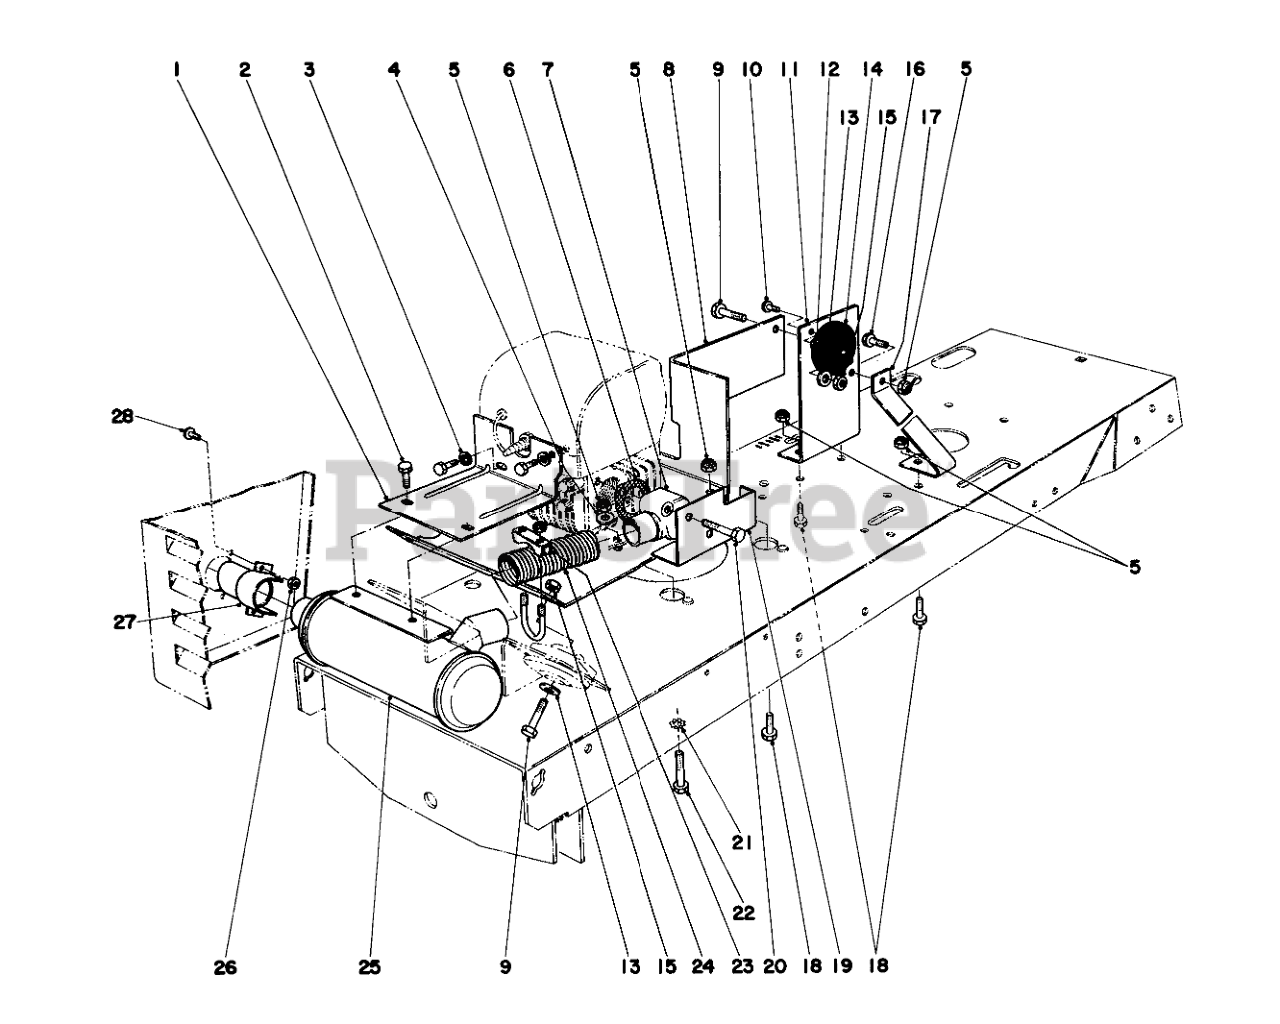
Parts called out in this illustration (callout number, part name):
1	Hanger Muffler
2	SCREW-HH
3	WASHER-LOCK/SP
4	WASHER-PLAIN
5	NUT-LOCK, CONE
6	Gasket
7	Elbow Exhaust
8	Engine Mount
9	SCREW-HH
10	SCREW-PTH
11	Mount Rear
12	NUT-LOCK, SIDE
13	WASHER-FLAT
14	Mount Rubber
15	NUT-LOCK, SIDE
16	SCREW-HH
17	Brace
18	SCREW-HH
19	Baffle Heat
20	Capscrew
21	WASHER-LOCK
22	SCREW-HH
23	Muffler Clamp
24	Exhaust Tubing
25	Muffler
26	NUT-LOCK, SIDE
27	Exhaust Tip
28	SCREW-PPH
